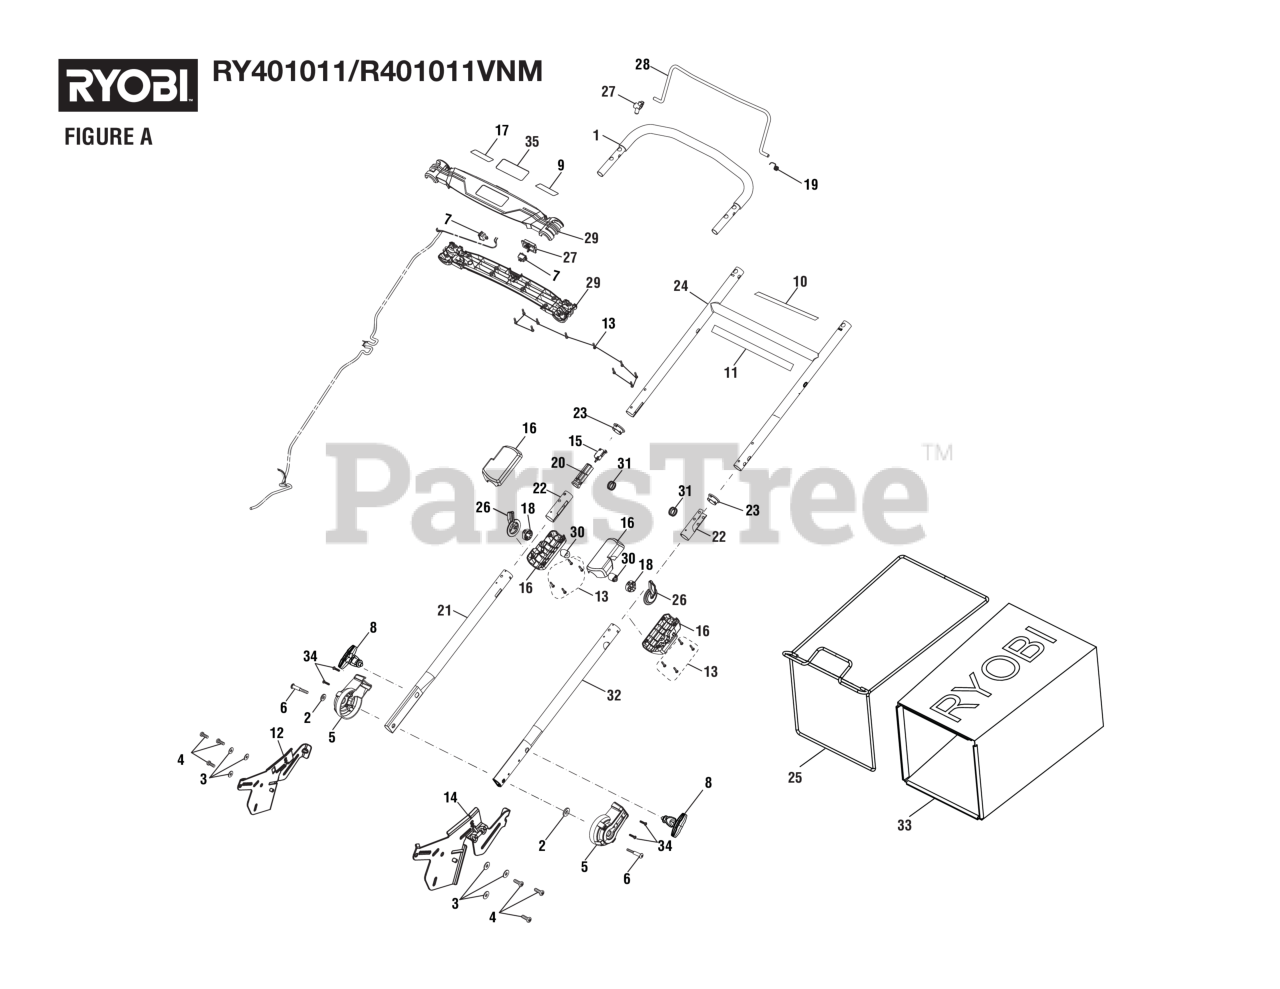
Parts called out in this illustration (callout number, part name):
1	Upper Handle Assembly
2	Washer (ID8.5 x OD20.5 x 2 mm x 2t)
3	Washer (1/4 in., Type A)
4	Screw (1/4-15 x 3/4 in., T30 Torx Pan Hd.)
5	HINGE SHROUD
6	Screw (M8 x 33 mm, Hex Hd.)
7	Stop Switch (Momentary Contact)
8	SPRING PIN ADJUSTMENT ASSEMBLY
9	Start Label (Left)
10	Lithium Label
11	Handle Extended Label
12	STAMPING, RIGHT HANDLE BRACKET
13	Screw (M4 x 18 mm, T20 Torx Pan Hd.)
14	STAMPING, LEFT HANDLE BRACKET
16	Handle Latch Assembly
17	Start Label (Right)
18	Disc Holder
19	Torsion Spring
20	Switch Plug Housing
21	STEEL TUBE,LOW RIGHT HANDLE TUBE
22	Handle Tube Bushing
23	Handle Tube Bushing (Small)
24	UPPER HANDLE TUBE W/ LABEL
25	FRAME, 20 INCH GRASS BAG, BLACK
26	Handle Latch
27	ACTUATOR SWITCH AND SAFETY BUTTON ASSEMB
28	Bail Handle
29	UPPER HANDLE SUPPORT ASSEMBLY W/ LABELS
30	Side Compression Disc
31	Handle Compression Spring
32	STEEL TUBE,LOW LEFT HANDLE TUBE
33	GRASS BAG
34	Screw (M4 x 20 mm, T20 Torx Pan Hd. S.T.)
35	Logo Label (Guard)
